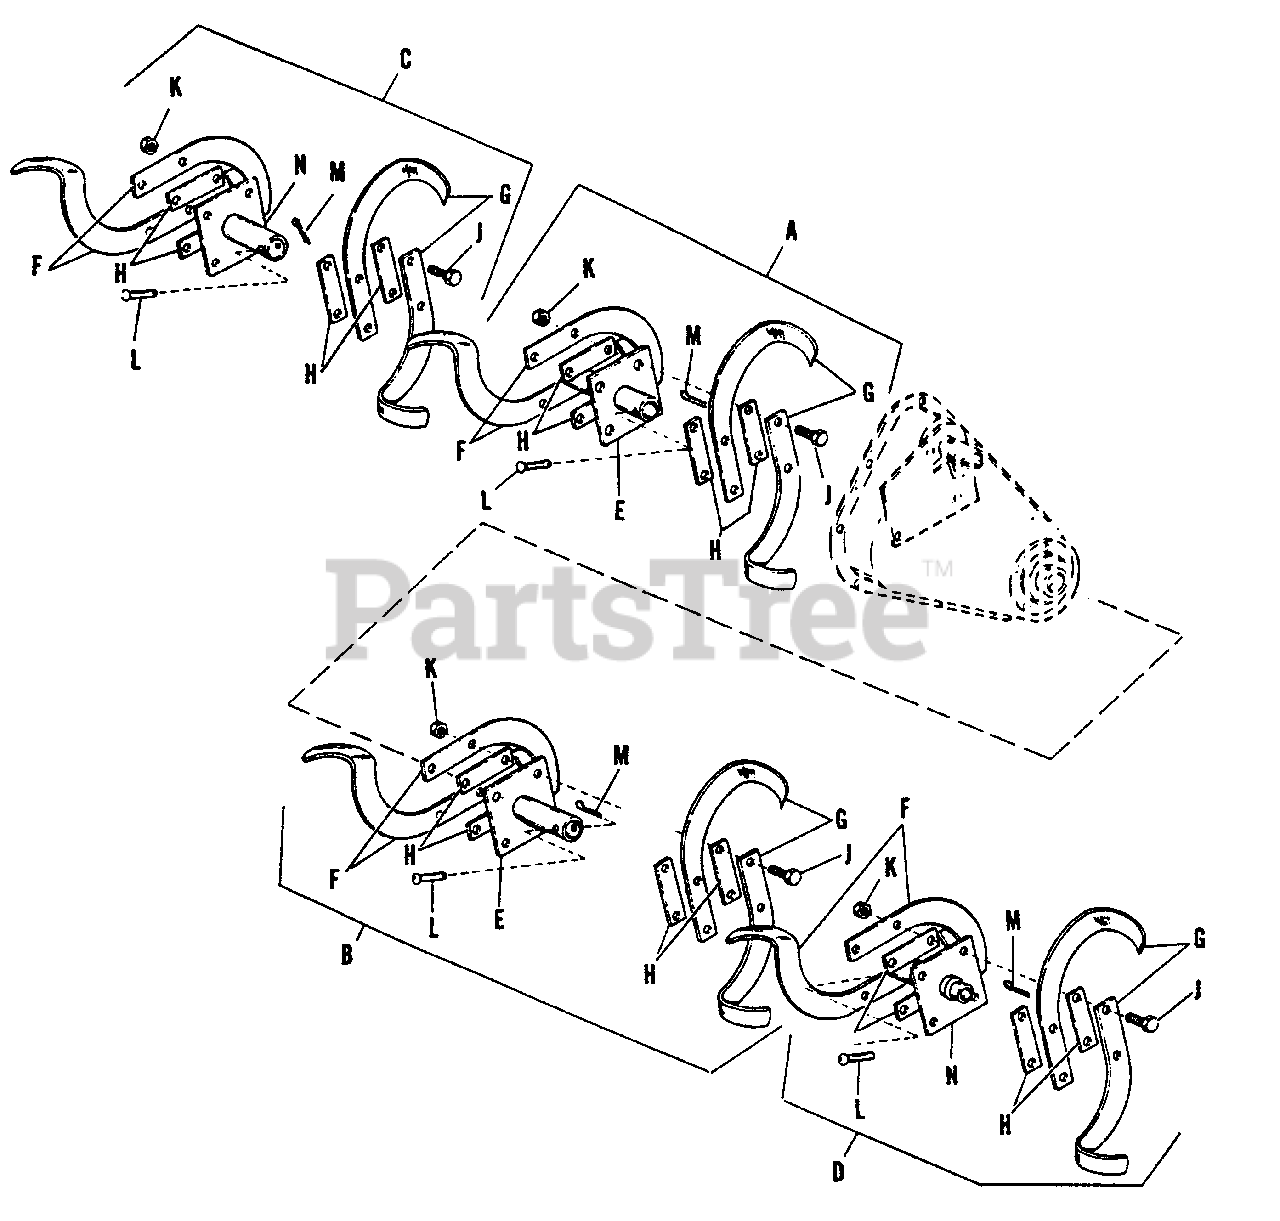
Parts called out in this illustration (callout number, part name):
A	Blade Assembly, Right Hand Inner Tine
B	Blade Assembly, Left Hand Inner Tine
C	Blade Assembly, Right Hand Outer Tine
D	Blade Assembly, Left Hand Outer Tine
E	Plate Assembly, Tine, Inner
F	Blade, Tine, Right Hand
G	Blade, Tine Left Hand
J	Capscrew, Hex, 7/16"-20 NC x 1 3/4" lg.
K	Nut, Lock, Hex, Full, 7/16"-20 NC
L	Pin, Tine Shaft
M	Pin, Cotter, 1/8" diameter
N	Plate Assembly, Tine, Outer
